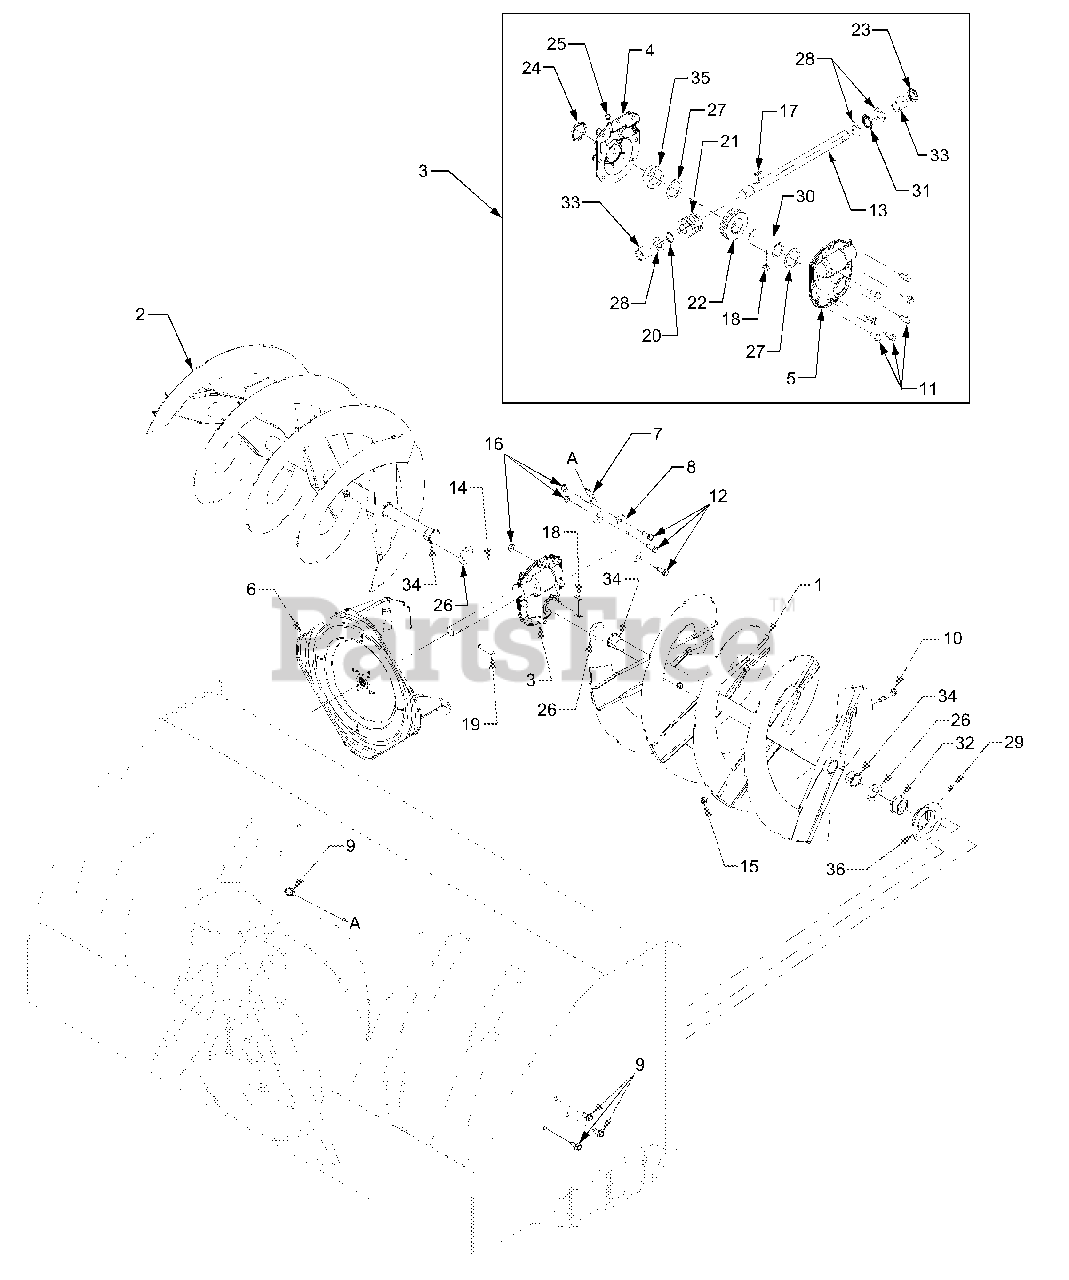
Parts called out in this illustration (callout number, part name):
4	Housing, Gear - RH (Includes Ref. Nos. 24 and 35)
5	Housing, Gear - LH (Includes Ref. Nos. 24 and 35)
6	Impellar Assembly
7	Bracket, Gear Box Support
10	Shear Bolt, 5/16-18 x 1-3/4
11	Screw, Hex Wash. Hd. Tapp 5/16-18 x .75
12	Screw, Hex Cap 5/16-18 x .875 GR5
13	Shaft, Input
14	Axle, Spiral, 1" x 53.12
15	Nut, Hex Insert Lock, 5/16-18
16	Nut, Hex Flange Lock, 5/16-18
17	Key, Hi Pro, 3/16 x 3/4
18	Key, Woodruff, 1/4 x 3/4
19	Pin, Spirol, 5/16 x 1.75
20	Ring, Snap, .875 Shaft
21	Gear, Worm
22	Gear, Worm
23	Seal, Oil
24	Seal, Oil
25	Plug, 1/4 x .437
26	Washer, Flat, 1.0 x 1.75 x .1
27	Washer, Flat, 1.5 x 2.0 x .3
28	Washer, Flat, .88 x 1.4 x .125
29	Lube Fitting, 3/16 Drive
30	Shaft, Worm Gear
31	Bearing, Thrust
32	Bearing, Flange w/Flats
33	Bearing, Sleeve
34	Bushing, Flange
35	Bearing, Flange
